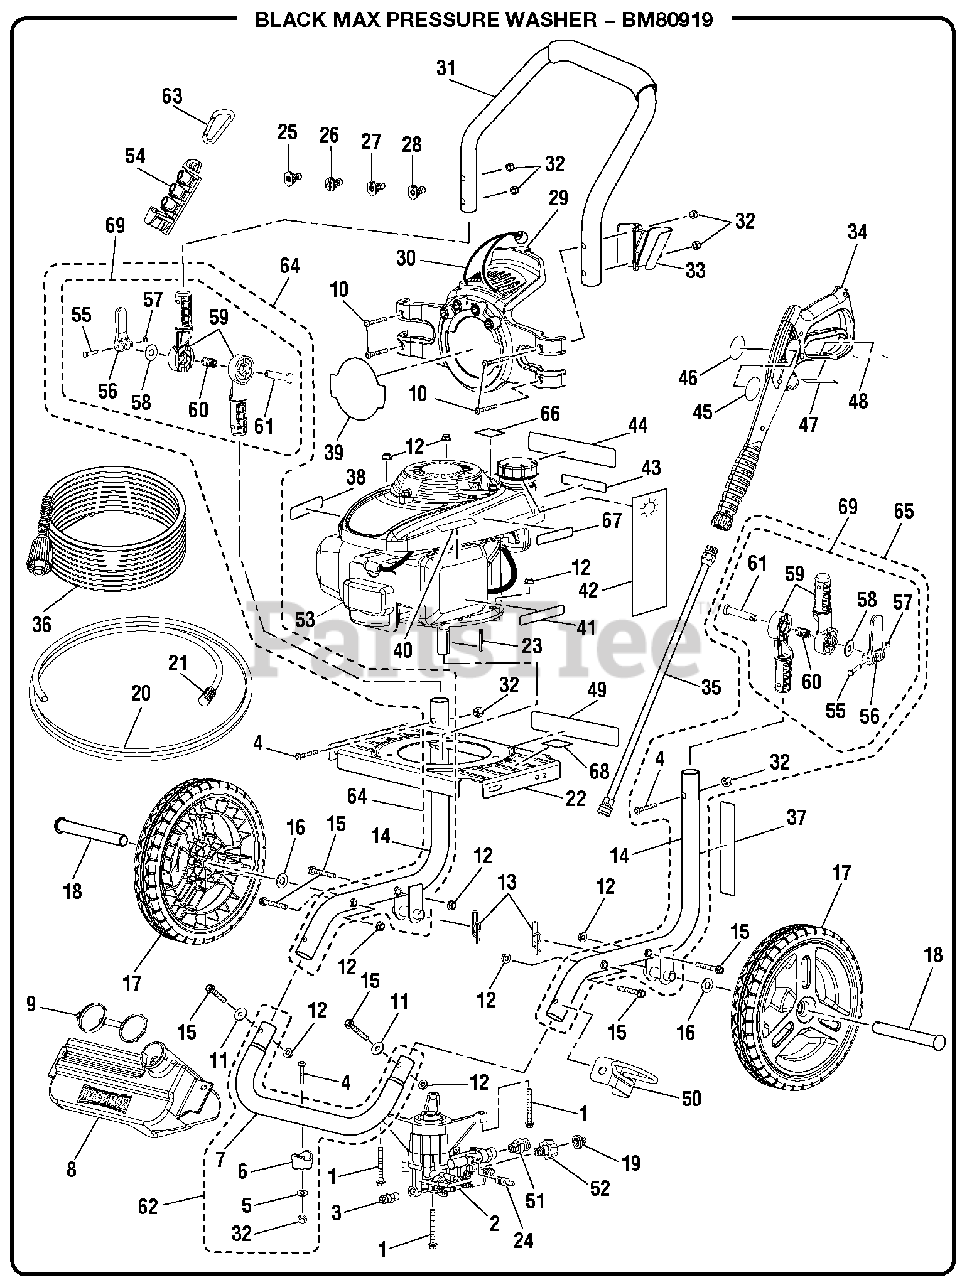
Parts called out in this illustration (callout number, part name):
1	Bolt (M8 x 60 mm, Flange Hd.)
2	Pump
3	Thermal Release Valve
4	Screw (1/4-20 x 1.85 in., T30 Torx Hd.)
5	Washer (1/4 in.)
7	Front Frame
8	Soap Tank
9	Soap Tank Cap
10	Screw (1/4-20 x 2.27 mm, Pan Hd.)
11	Washer (5/16 in.)
12	Hex Nut (M8 x 1-1/4 in.)
13	Ring Clip
14	Main Frame Assembly
15	Bolt w/Washer (M8 x 55 mm, Hex Hd.)
16	Washer (1/2 in.)
19	Filter Screen (Pump Inlet)
20	Chemical Siphon Tube
21	Chemical Siphon Filter
22	Engine Plate
23	Output Shaft Key (3/16 in. x 40 mm)
24	Detergent Suction Kit
25	40deg Nozzle
26	Soap Nozzle
27	25deg Nozzle
28	0deg Nozzle
29	Hose and Nozzle Holder Assembly
30	Bungee Cord and Bead Assembly
31	Handle w/Foam
32	Lock Nut (1/4-20)
33	Wand Holder
34	Trigger Handle Assembly
35	Extension Wand
36	Hose (25 ft., 3000 psi)
37	Label (Pump Quick Start)
38	Label (Hot Muffler)
39	Label (Performance)
40	Label (Inquires)
41	Label (Engine Quick Start)
42	Label (Oil Hang Tag)
43	Label (UL Fire Warning)
44	Label (Warning)
45	Label (Wand Warning)
46	Label (Wand Logo)
47	Label (Warning)
48	Label (Wand Rating)
49	Data Label
50	Wand Holder
51	Outlet Tube
52	Inlet Tube
53	Engine
54	Nozzle Holder
56	Handle Lock Lever
59	Locking Pivot Bracket
61	Locking Cam Pin
62	Front Frame Assembly (Inc. Key Nos. 5-7 and 32)
63	Spring Clip
64	Frame Assembly w/Lock Lever, Left
65	Frame Assembly w/Lock Lever, Right
66	Label (E85)
67	Label (Release Pressure)
68	Label (Engine Lubricant)
69	Lock Lever Assembly
